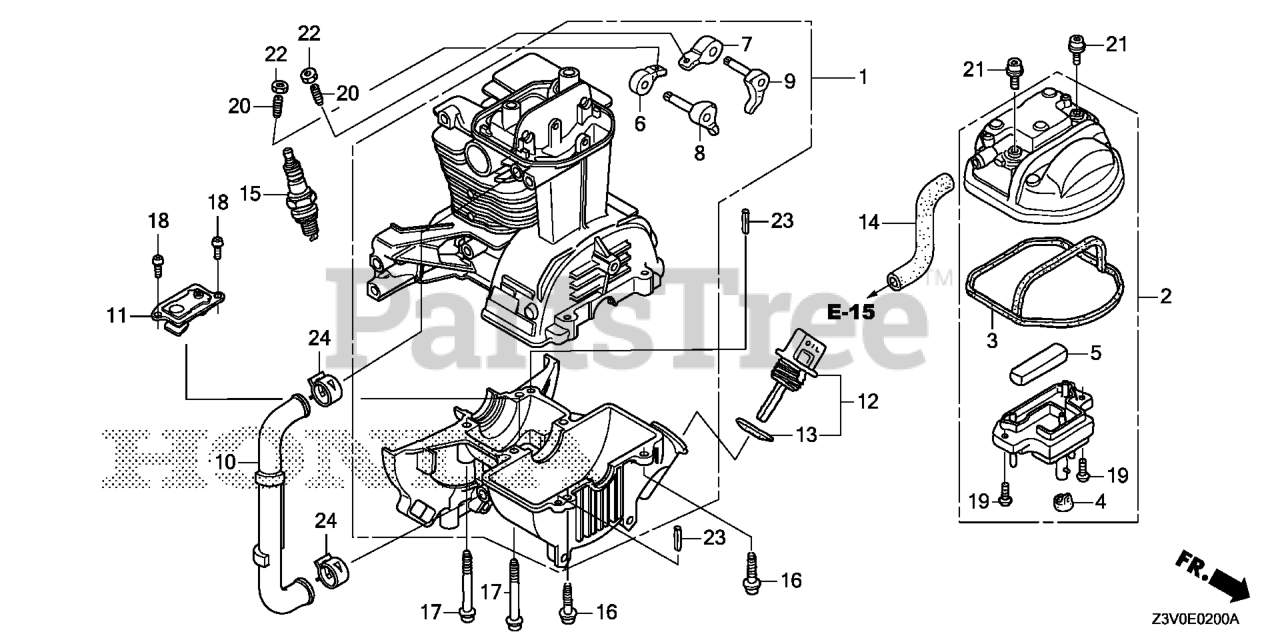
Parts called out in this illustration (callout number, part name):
1	CRANKCASE SET
2	COVER, CYLINDER HEAD
3	SEAL, HEAD COVER
4	GROMMET, HEAD COVER
5	FILTER, BREATHER
6	ARM, IN. VALVE ROCKER
7	ARM, EX. VALVE ROCKER
8	LIFTER, IN. VALVE
9	LIFTER, EX. VALVE
11	PLATE ASSY., OIL OUTLET VALVE
12	CAP ASSY., OIL FILLER
13	GASKET, OIL FILLER CAP
14	TUBE, BREATHER
15	SPARK PLUG (CMR4H) (NGK)
15	SPARK PLUG (CMR5H) (NGK)
15	SPARK PLUG (CMR6H) (NGK)
16	BOLT, SOCKET (5X20)
17	BOLT, SOCKET (5X39)
18	SCREW, PAN (4X8)
19	SCREW, PAN (4X8)
20	SCREW, TAPPET ADJUSTING
21	BOLT, SOCKET (5X12)
22	NUT, TAPPET ADJUSTING
23	PIN, SPRING (4X10)
24	CLAMP, TUBE (D12)
